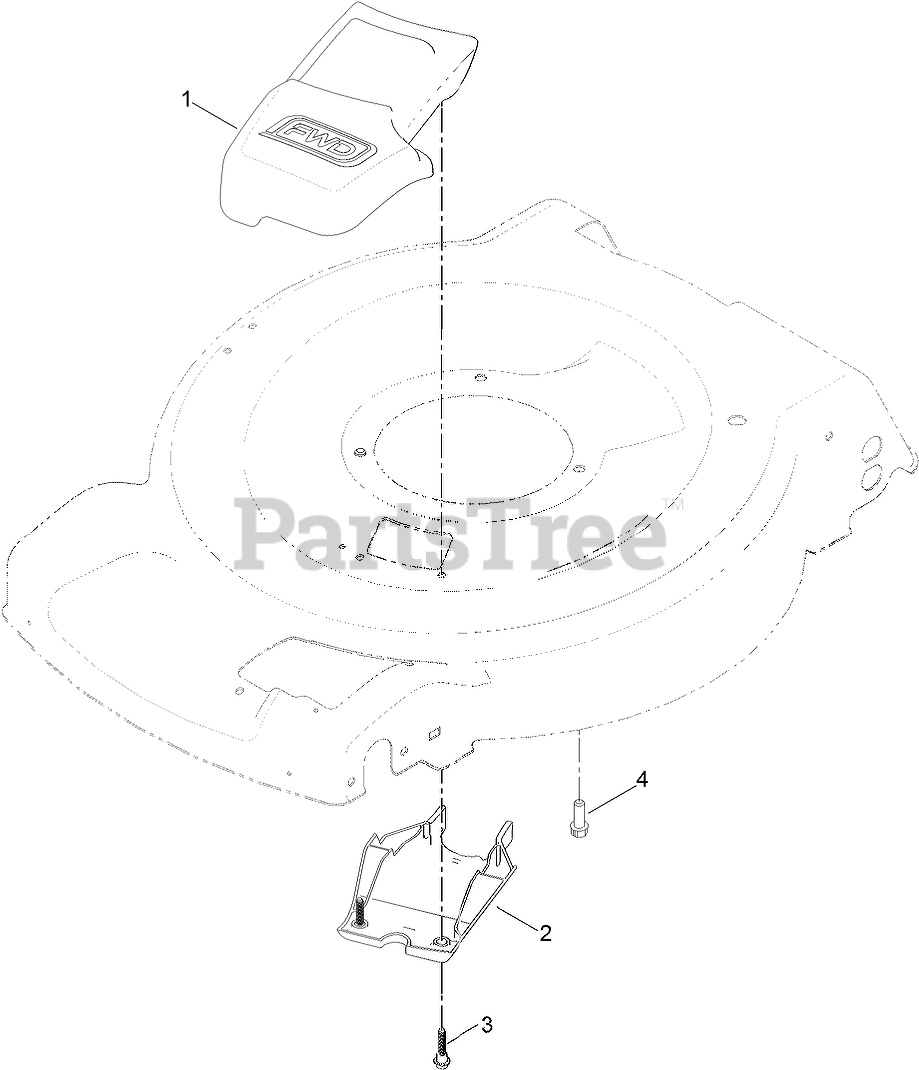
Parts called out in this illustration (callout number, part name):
1	COVER-BELT, FWD
2	COVER-BELT, FRONT LOWER
3	SCREW-SHOULDER, HHF
4	SCREW-TAPTITE
